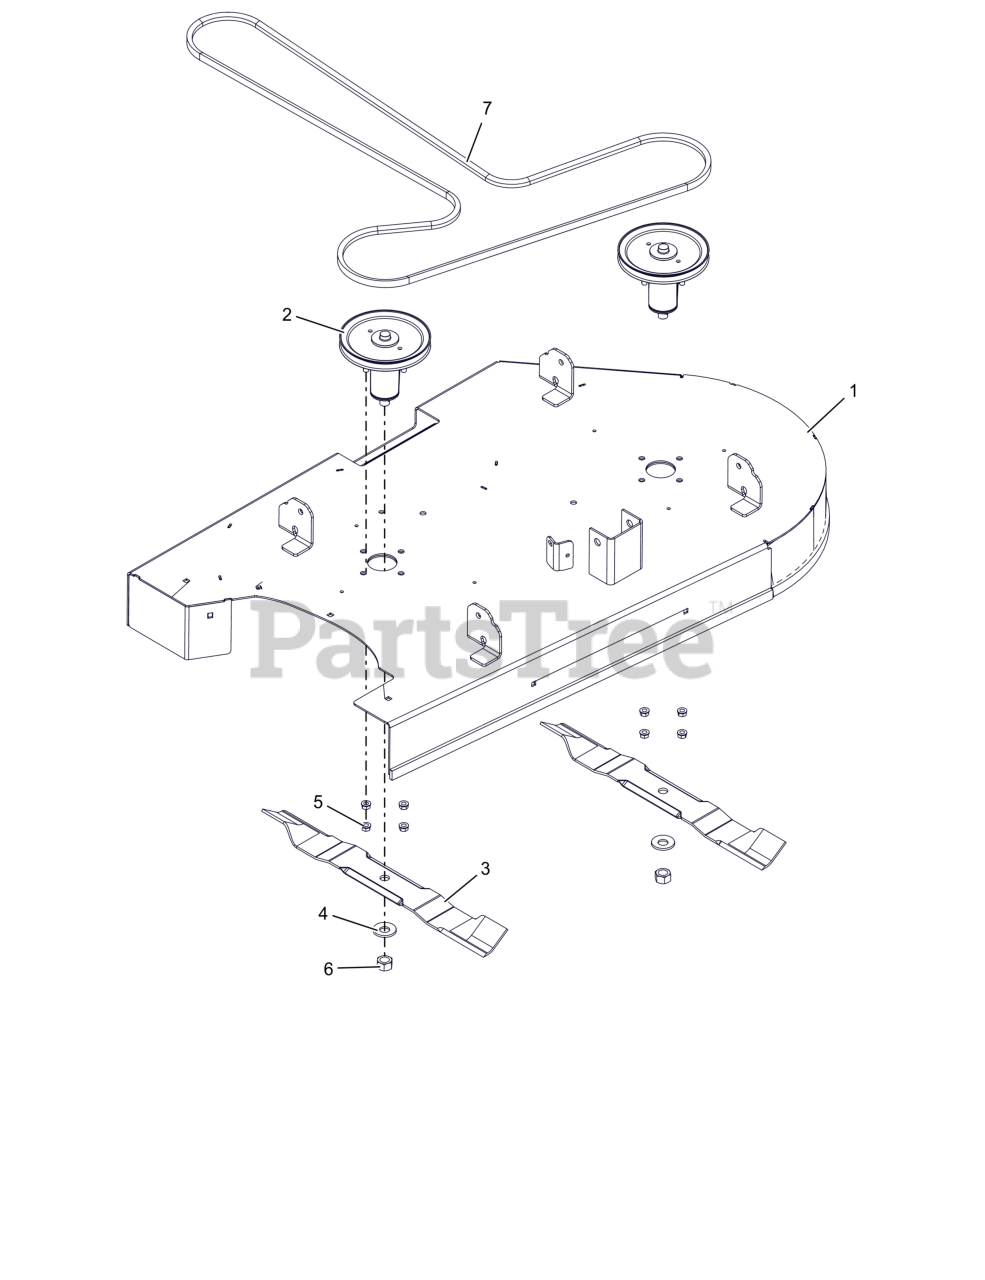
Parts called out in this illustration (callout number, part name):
1	WLDMT, DECK - 42 EDGE CE (ORANGE)
2	KIT- DECK SPINDLE ASSM
3	BLADE, 21" 35 DEG
4	WSHR-BLVL .669X1.535X.138
5	NUT,LK-CTR-FLG .31-18 GF ZCC
6	NUT-STD .625-18 ZCC
7	V-BELT, HA-WRAPPED
